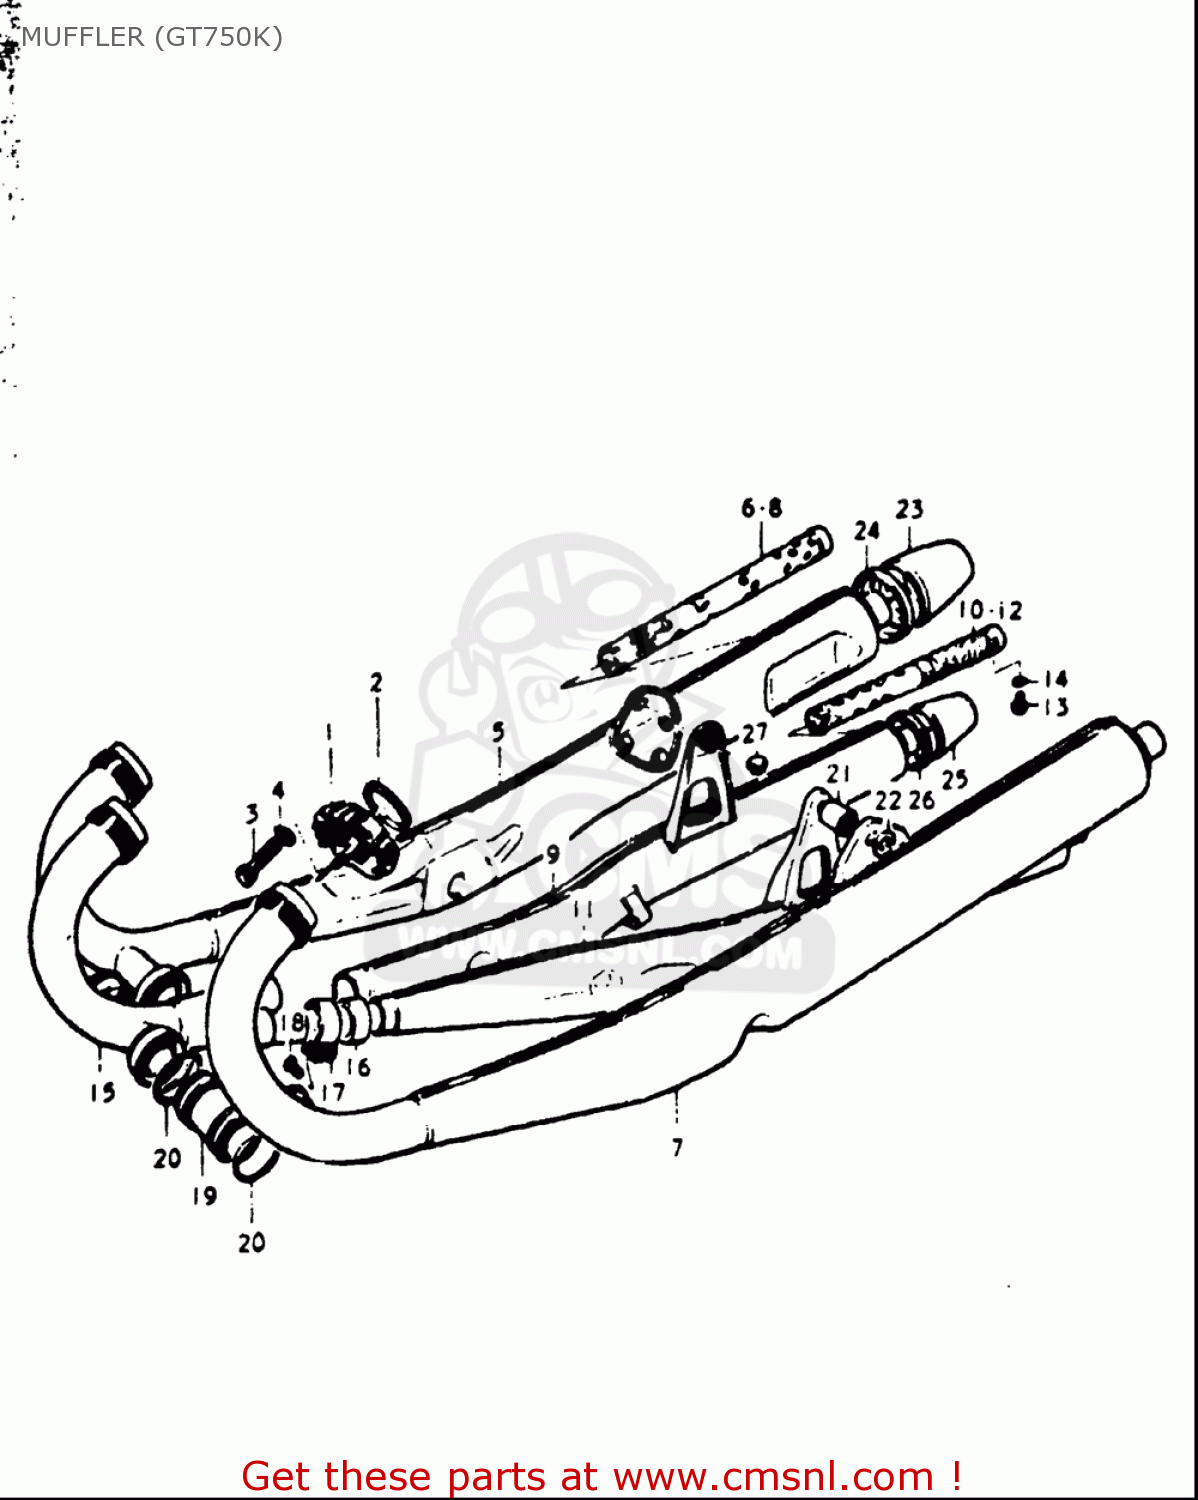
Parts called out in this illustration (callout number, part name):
2	GASKET,EXHAUST PIPE (NAS)
3	BOLT
4	WASHER,LOCK
6	PIPE,BAFFLE
8	PIPE,BAFFLE
10	PIPE,BAFFLE CTR
12	PIPE,BAFFLE CTR
13	SCREW(5X12)
14	WASHER,LOCK
16	CONNECTOR,MUFFLER
17	CLAMP
18	SCREW
20	O RING(D:2.6,ID:39.7)
21	BUSH
22	WASHER
26	CLIP, REAR COVER CENTER
27	CUSHION
